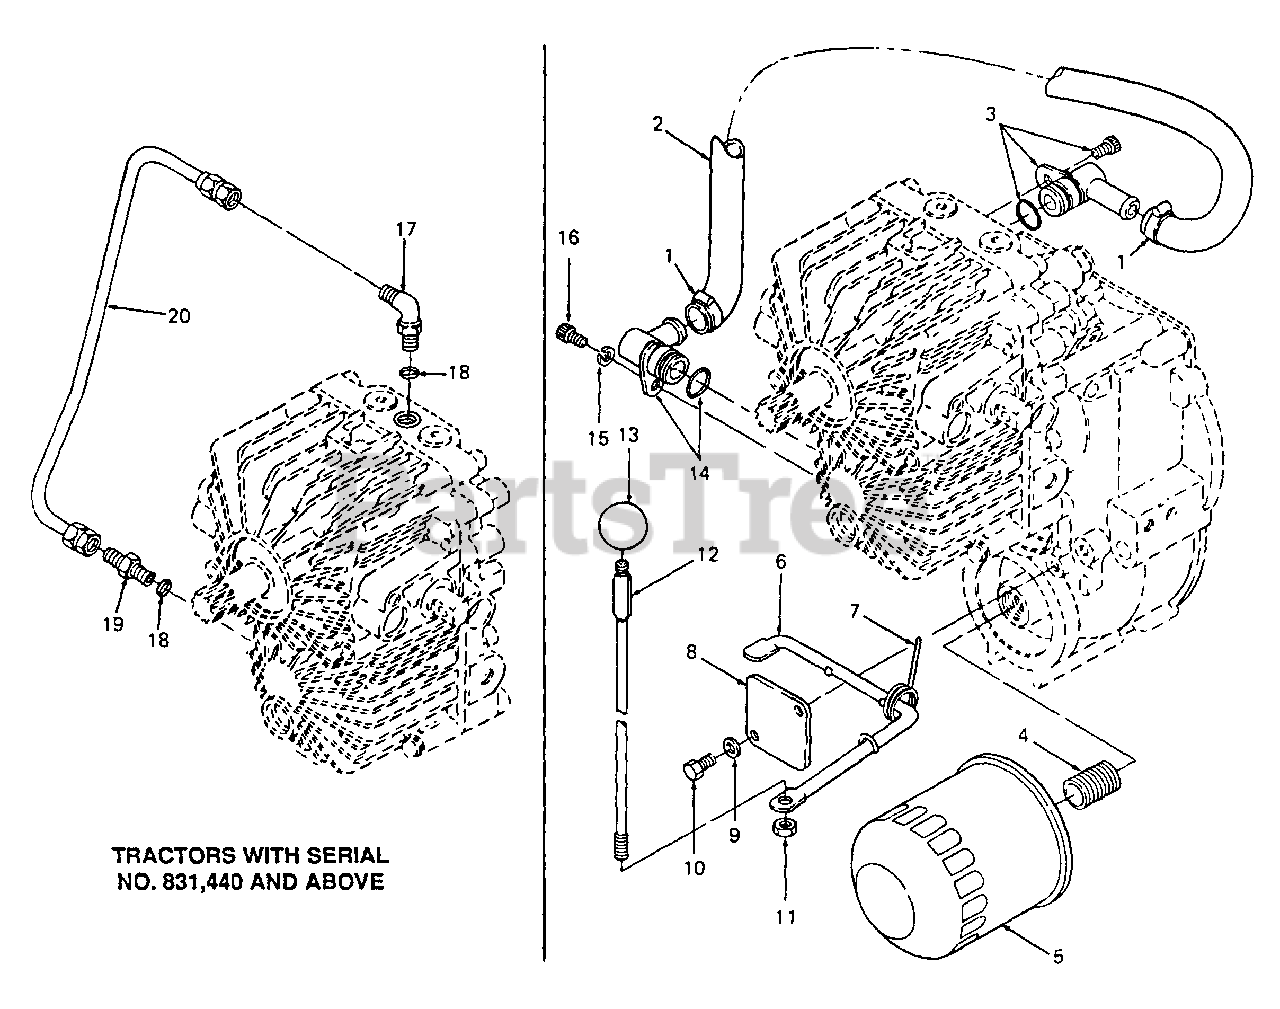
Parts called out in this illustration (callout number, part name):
1	Cable Tie
2	Line, Pickup
3	Fitting Assembly
4	Nipple, Oil Filter
5	Filter, Oil
6	Rod, Dump Valve Lower
7	Spring, Torsion
8	Plate, Retaining
9	Washer, Lock, 1/4
10	Screw, Hex Cap, 1/4-20 X .50 Lg GR5
11	Nut, Hex Top Lock, 1/4-20
12	Rod, Dump Valve Upper
13	Knob, Ball
14	Fitting Assembly
15	Washer, Lock, 1/4
16	Screw, Socket Head, 1/4-20 X .65 Lg
17	Elbow, 90 Degree Tube
18	O-Ring, 3/8 OD Tube
19	Connector, 37 Degree Tube
20	Line, Metal Pickup
